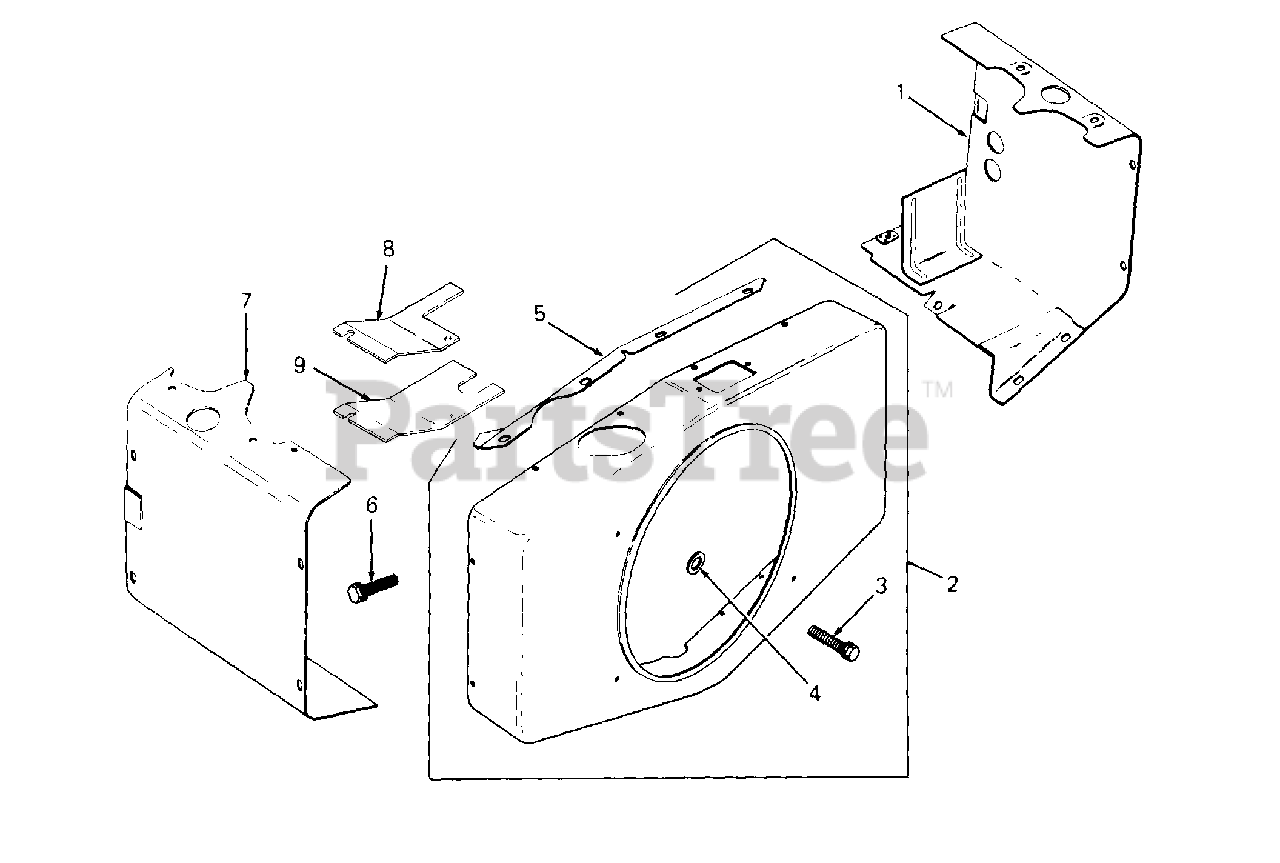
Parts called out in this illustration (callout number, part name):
1	Baffle, #1 Cylinder Head
2	Kit, Blower Housing
3	Screw, Self Tap, 1/4-20 X 5/8
4	Washer, Flat, 1/4
5	Support, Upper Housing
6	Screw, Hex Wash Hd, 1/4-20 X 7/16
7	Baffle, #2 Cylinder Head
8	Baffle, #2 Cylinder Top
9	Baffle, Pump
